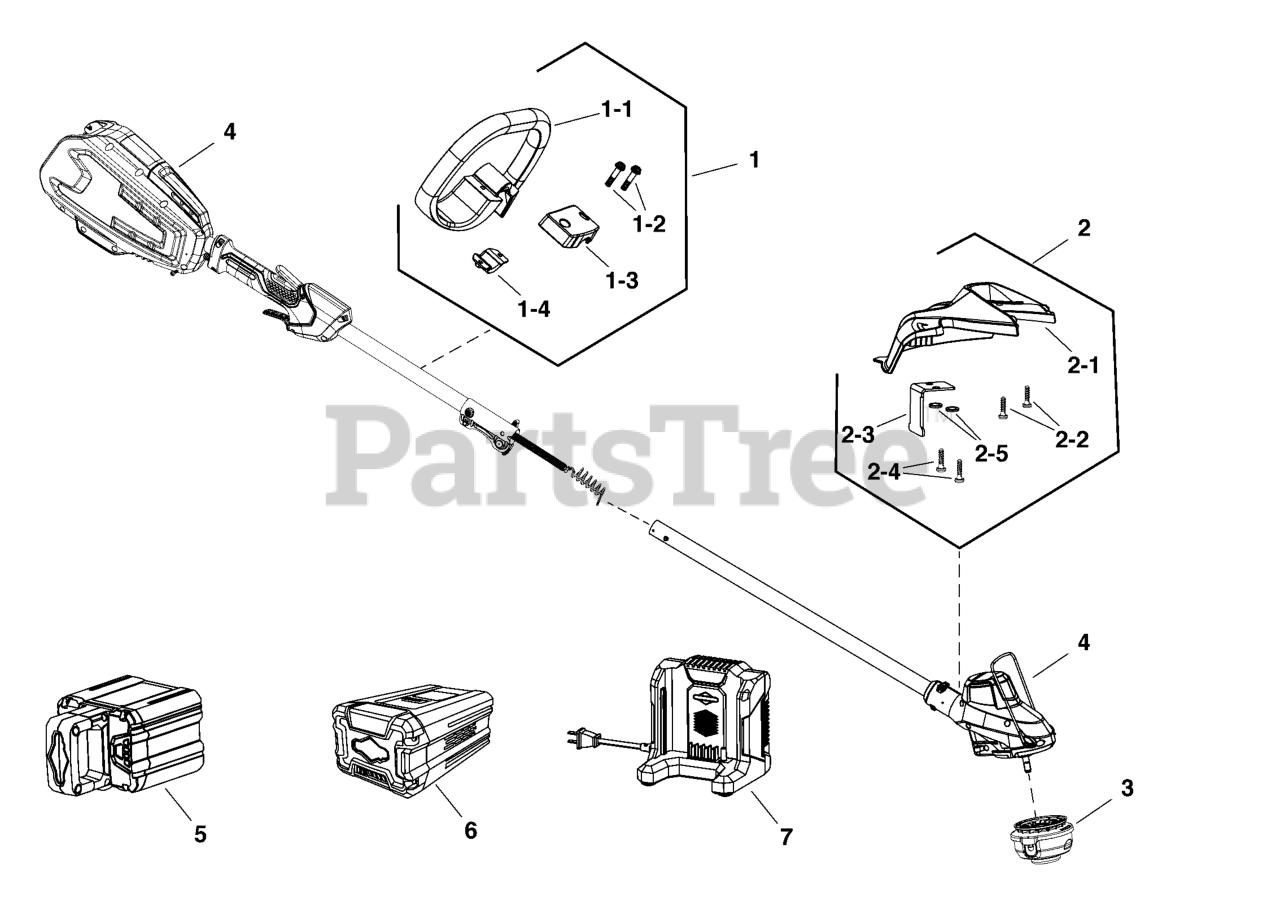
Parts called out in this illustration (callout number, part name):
1	HANDLE ASSEMBLY
1-1	HANDLE, Auxiliary
1-2	SCREW
1-3	COVER, Handle
1-4	CLAMP
2	GUARD ASSEMBLY
2-1	GUARD
2-2	SCREW
2-3	BLADE, String
2-4	SCREW, Self Tapping
2-5	WASHER, Spring
3	TRIMMER HEAD ASSEMBLY
4	* STRING TRIMMER, 48V
5	* BATTERY, 2.0, 48V
6	* BATTERY, 5.0, 48V
7	* BATTERY CHARGER, 48V
